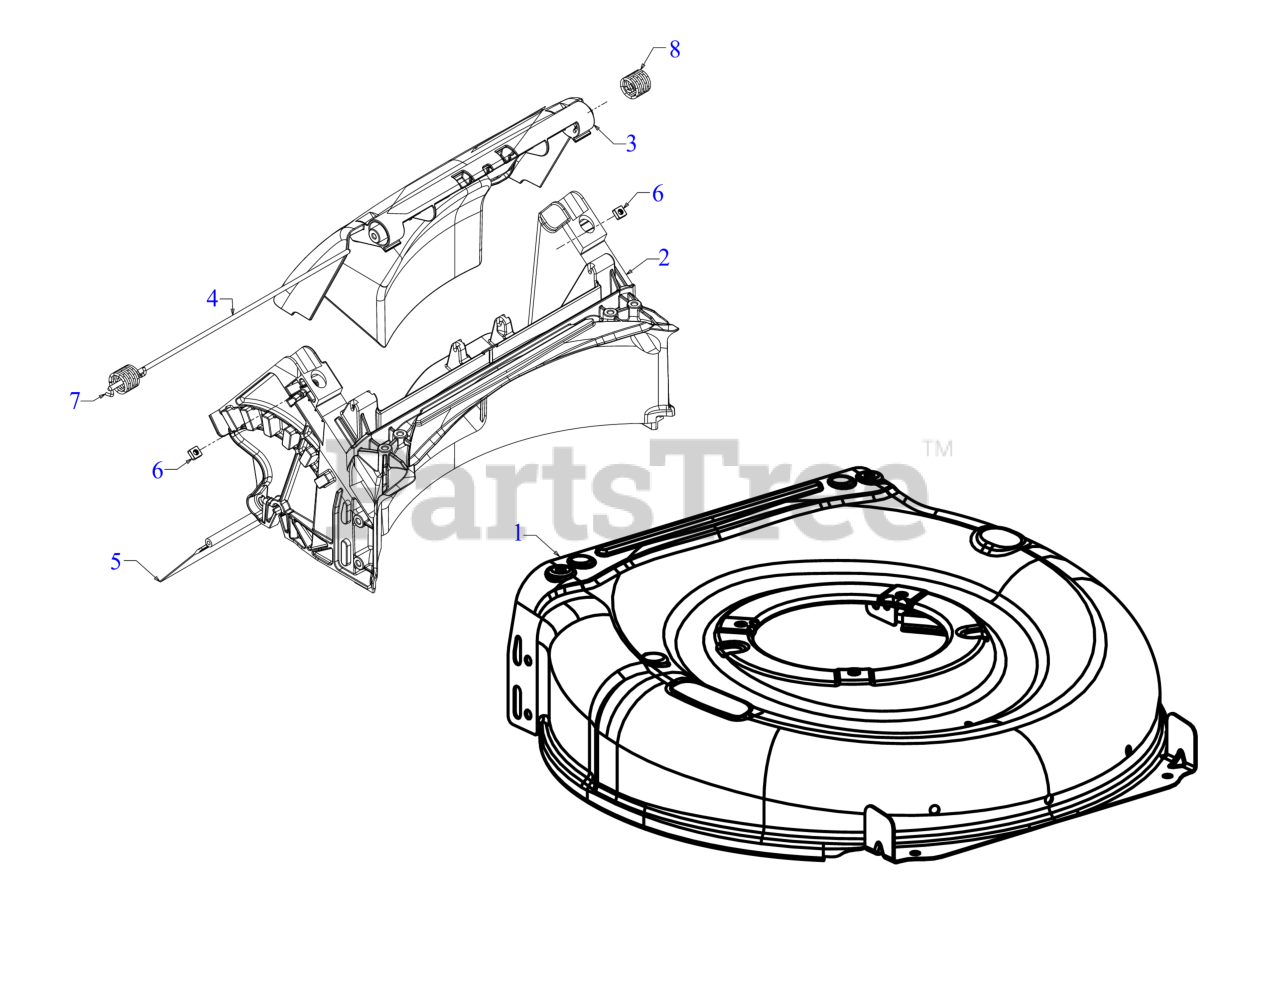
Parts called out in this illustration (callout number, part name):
2	REAR BAG DOOR ASSEMBLY
3	REAR BAG DOOR ASSEMBLY
4	REAR DOOR PIVOT ROD
5	TRAILSHIELD
6	SQUARE NUT 1/4-20
7	TORSION SPRING (RH)
8	TORSION SPRING (LH)
